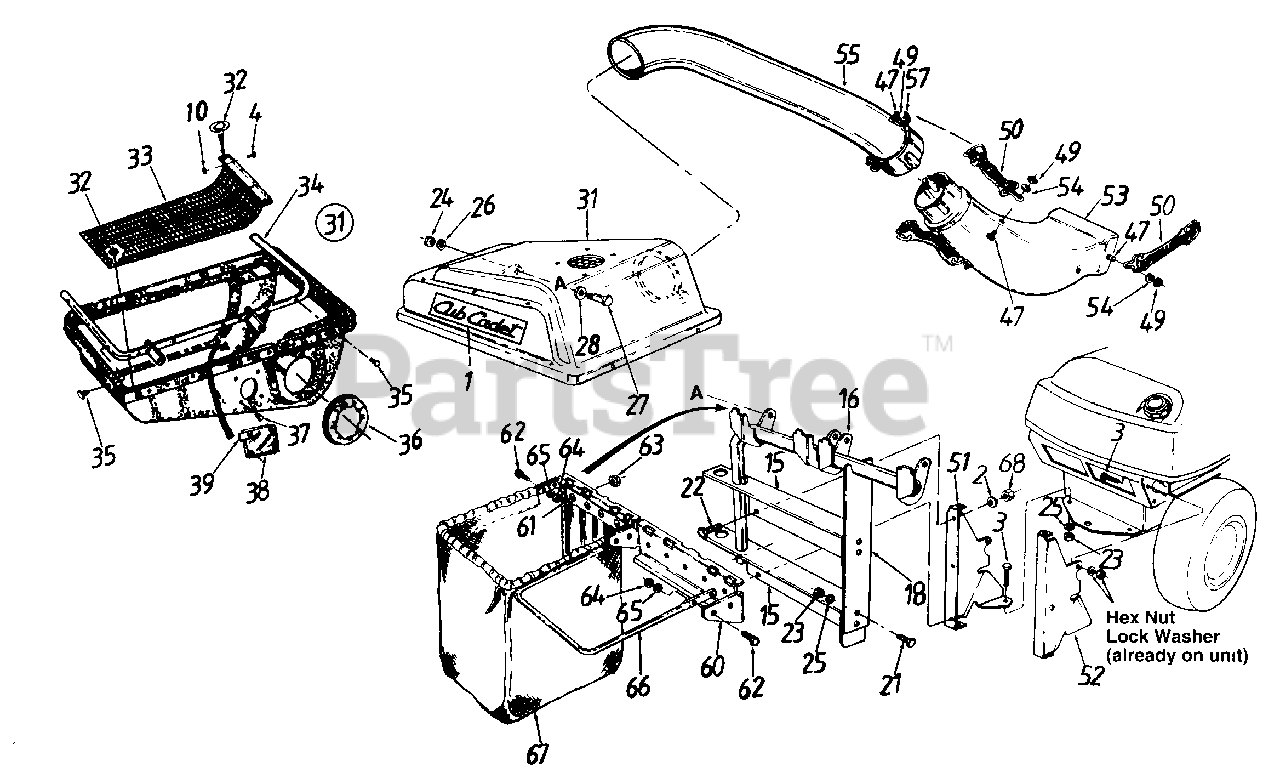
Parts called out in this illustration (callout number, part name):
1	Cub Cadet Name Plate
2	Fl-Wash. 1/4" I.D.
3	Hex Bolt 5/16-18 x 1.0" Lg.
4	Pop Rivet .188 Dia.
10	Flat Wash. 1/4" I.D.
21	Hex Bolt 5/16-18 x .75"
22	Hex Bolt 1/4-20 x .62" Lg.- Grade 5
23	Hex Nut 5/16-18 Thd.
24	Hex Nut 3/8-16 Thd.
25	L-Wash. 5/16" I.D.
26	L-Wash. 3/8" I.D.
27	Shld. Bolt 3/8-16 x .50" Dia.
28	Bell-Wash..505" I.D. x 1.0" O.D.
31	Grass Catcher Cover Ass'y.
32	Twist Fastener
35	Hex AB-Tap Scr. 1/4 x .62"
36	Seal - 7"
37	Truss B-Tap Scr #10 x .5" Lg.
38	Plastic Plate
39	Speed Nut
47	Hex Bolt 1/4-20 x 625"
49	Hex Ins L-Nut 1/4-20 Thd
50	Retainer Strap Ass'y
51	Catcher Support Brkt.- L.H.
52	Catcher Support Brkt - R H.
53	Discharge Chute
54	L-Wash..27" I.D.
55	Catcher Tube
57	Retainer Hook Brkt
61	Truss Mach. Scr. #10-24 x 5"
62	Hex Bolt 1/4-28 x .88"
63	Hex Sems Nut #10-24 Thd.
64	Hex Nut 1/4-28 Thd
65	L-Wash. 1/4" I.D.
67	Grass Catcher Bag
68	Hex L-Nut 1/4-20 Thd.
